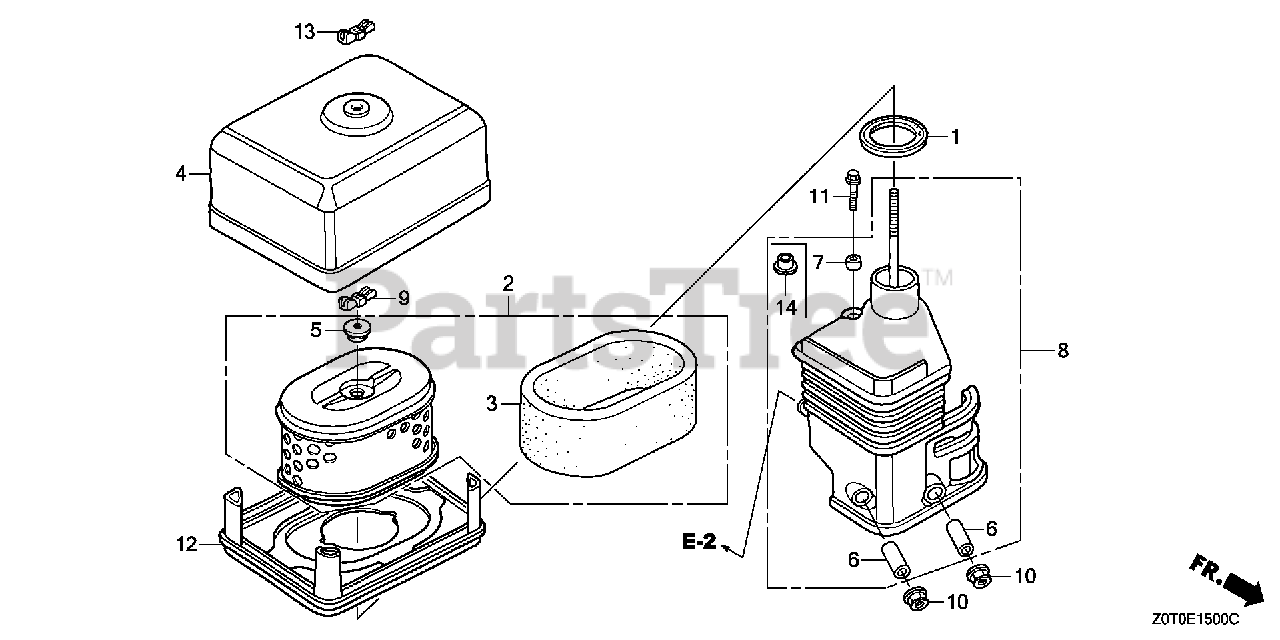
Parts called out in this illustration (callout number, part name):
1	GASKET, ELBOW
2	ELEMENT, AIR CLEANER (DUAL)
3	FILTER (OUTER)
4	COVER, AIR CLEANER
5	GROMMET, AIR CLEANER
6	COLLAR, AIR CLEANER Use from Engine SN 1786085.
7	COLLAR B, AIR CLEANER
8	ELBOW, AIR CLEANER
9	WINGNUT, TOOL BOX SETTING
10	NUT, FLANGE (6MM)
11	BOLT, FLANGE (6X20)
12	NOSE, MUFFLER
13	NUT, AIR CLEANER
